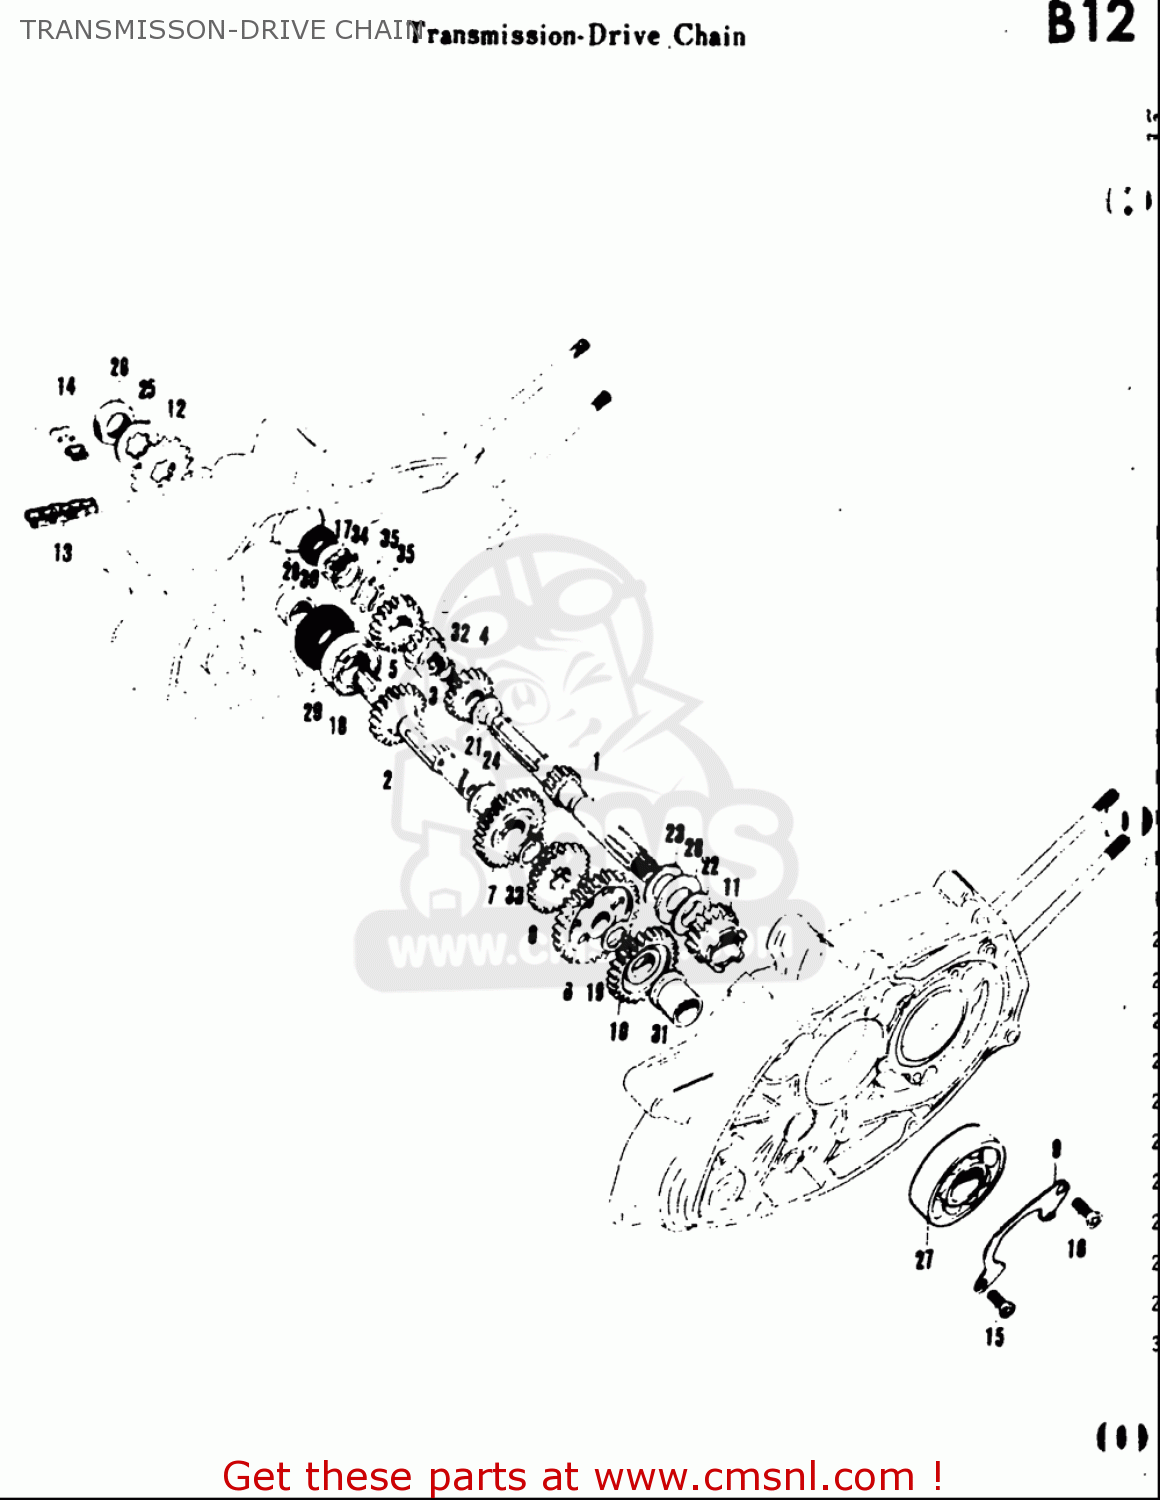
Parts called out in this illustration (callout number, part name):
3	GEAR,2ND DRIVE
4	GEAR,3RD DRIVE
5	GEAR,4TH DRIVE(NT:20)
6	GEAR,1ST DRIVEN
11	GEAR,KICK STARTER DRIVEN
15	SCREW
17	BEARING(12X28X8)
18	BEARING(20X47X14)
19	SHIM, 15X24X1.0
20	NUT
21	WASHER
22	WASHER (20.1X29.5X0.8)
23	WASHER(20X34X0.8)
25	WASHER,LOCK
27	BEARING(30X62X10)
28	BEARING(20.1X35X2.8)
29	SEAL,OIL(25X40X9)
30	SEAL,OIL(5.5X16X8)
32	CIRCLIP
33	CIRCLIP
34	RING,SNAP
